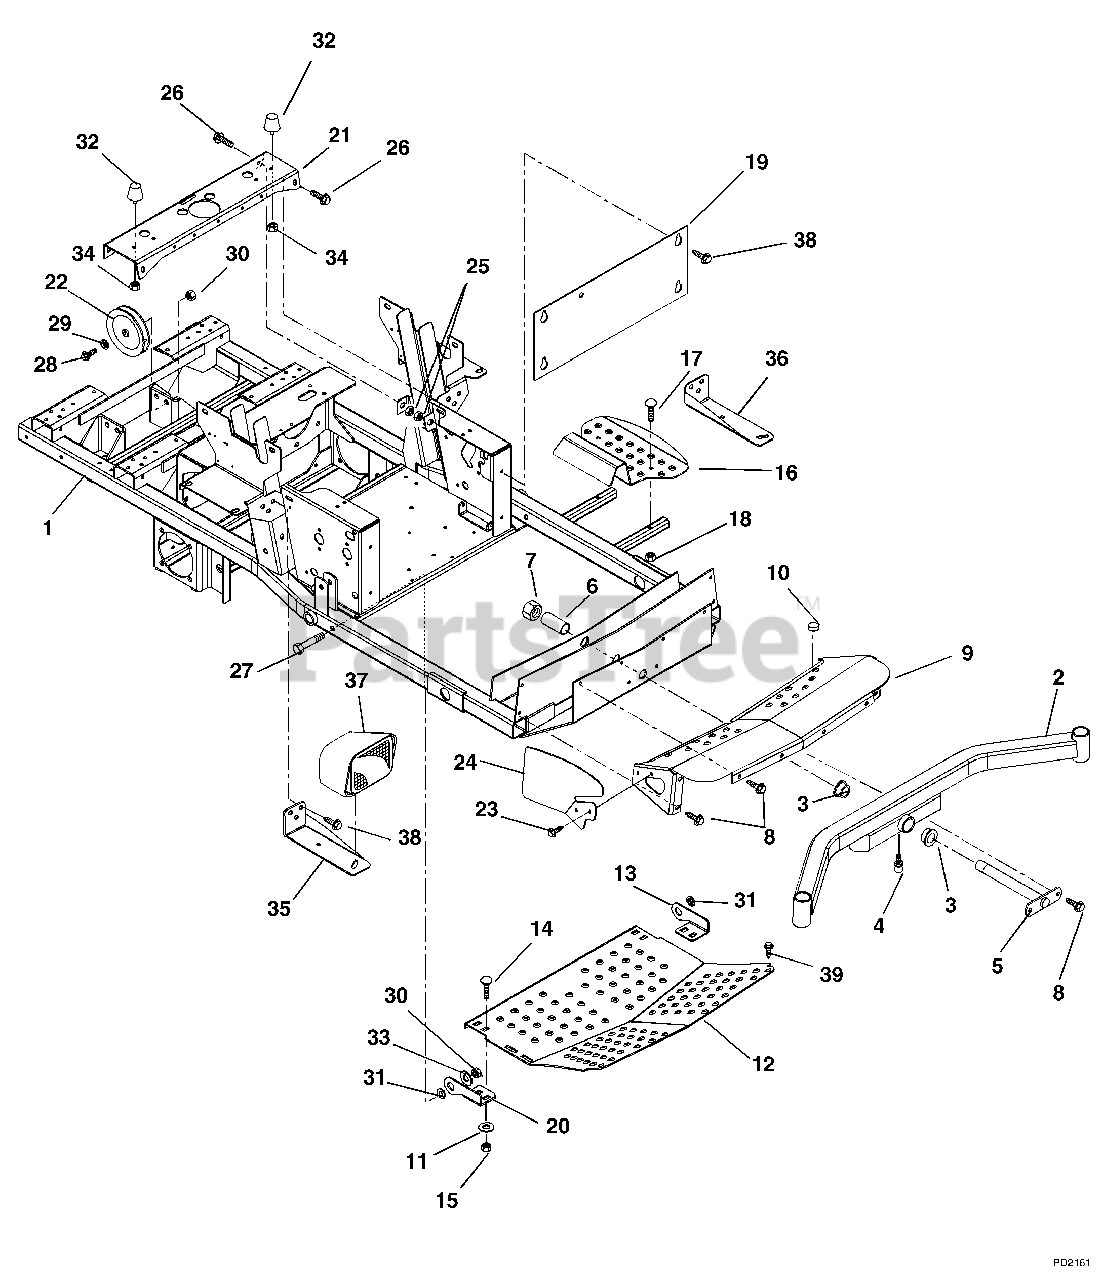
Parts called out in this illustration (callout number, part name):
1	Weldment, Frame
2	Weldment, Axle
3	Bushing-Flange 1.020 x 1.385 x .75 x 1.75
4	Fitting-Lube .25-28 x .256
5	Pin-Axle
7	Nut-Locking-Nylon 1.0-14
8	Screw-Tapping .38-16 x .75
9	Cover- Axle (Red)
10	Button, Bumper
11	Washer-Flat-Steel .38 x .875 x .083
12	Panel-Inspection
13	Hinge, Footboard Left Hand
14	Bolt-Round Head Square Neck .38-16 x 1.00 Grade 5
15	Nut-Locking-Nylon .38-16
16	Step-Ingress
17	Bolt-Round Head Square Neck .31-18 x 1.75 Grade 5
18	Nut-Locking-Nylon .31-18
19	Plate-Kick
20	Hinge, Footboard Right Hand
21	Channel-Cross
22	Pulley, Idler
23	Screw-Tapping .25-20 x .50 Hex Washer Head
24	Guard, Foot
25	Nut-Retainer .375-16 x .37
26	Bolt-Serrated Flange Washer Head .38-16 x 1.00
27	Bolt-Hex .50-13 x 3.25 Grade 5
28	Bolt-Hex .50-13 x 2.25 Grade 5
29	Washer-Flat-Steel .505 x .88 x .072
30	Nut-Locking-Nylon .50-13
31	Bushing-Flange .515 x .75 x .275 x 1.12
33	Washer-Flat-Steel .563 x 1.38 x .109
34	Nut-Locking-Flange .312-24
35	Weldment, Light Mount-Right Hand
36	Weldment, Light Mount-Left Hand
37	Headlight
38	Screw-Tapping .38-16 x .50 Hex Washer Head
39	Screw-Tapping .38-16X1.00 Hex Washer Head (309)
